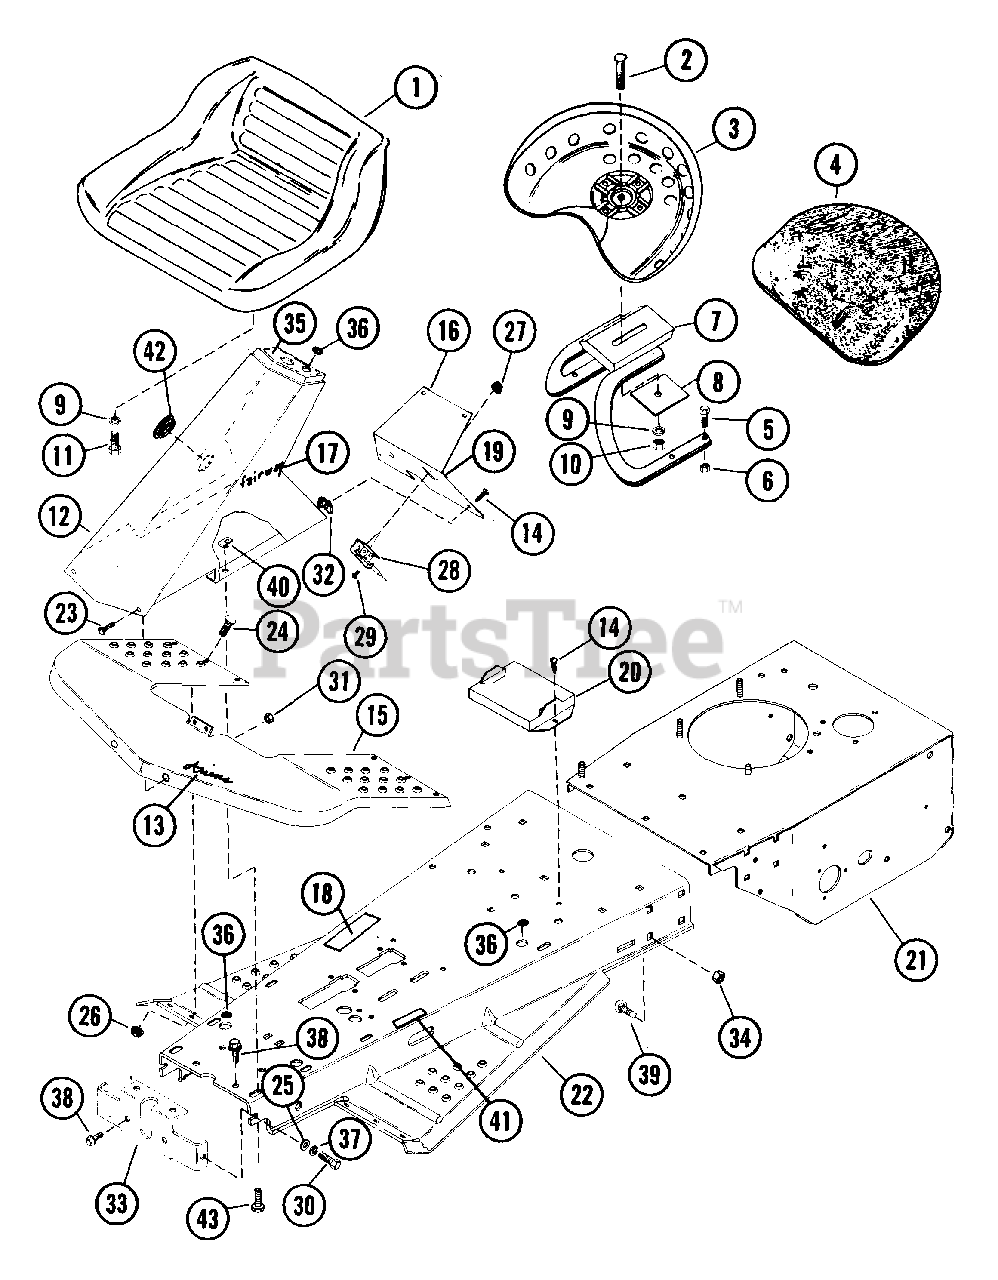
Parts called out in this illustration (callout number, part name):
1	SEAT
2	BLT-RDHDSQNK .50-13X1.25 PL
3	SEAT
4	SEAT COVER
5	BLT-HEX .31-18X1.50 PL GR2
6	NUT-LK .312-18 GR A PL
7	SEAT BRACKET
8	SEAT SUPPORT WASHER
9	WSHR-LK .500X.151 HVY PL
10	NUT .50-13 PL
11	BLT-HEX .50-13X1.25 PL GR2
12	STEERING COLUMN
13	ARIENS NAME PLATE
14	SCR-TAP 10-12X.50 CRPH PL A
15	FRONT FENDER
16	DASH PANEL ASSEMBLY
17	FAIRWAY NAME PLATE
18	CAUTION DECAL
19	DASH DECAL
20	BATTERY RETAINER
21	REAR FRAME
22	FRONT FRAME ASSEMBLY
23	SCR-MCH 10-24X.38 SLTOR PAN PL
24	SCR-SLTR-SERNK .25-20X.62 PL
25	WSHR-FL-STL .38X.875X.083 PL
26	NUT-LK-FLG .250-20 PL
28	THROTTLE CONTROL
29	RVT-POP.125 X .294 DOME
30	BLT-HEX .31-18X.75 PL GR2
31	NUT-KEPS 10-24 PL
32	NUT-SPEED U TYPE 10A
33	FRONT FRAME SUPPORT
34	NUT-FLG. .312-18 PL
35	PARKING BRAKE DECAL
36	GROMMET, .31 ID
37	WSHR-LK .312X.097 PL HVY
38	BLT-LK .31-18X.75 GR 5
39	BLT-RDHDSQNK .31-18X.75 GR5 PL
40	NUT-SPEED U-TY .312-18
41	MOWER IN-OUT LABEL
42	BUTTON PLUG 1.0
43	BLT-HEX .31-18X.50 PL GR2
